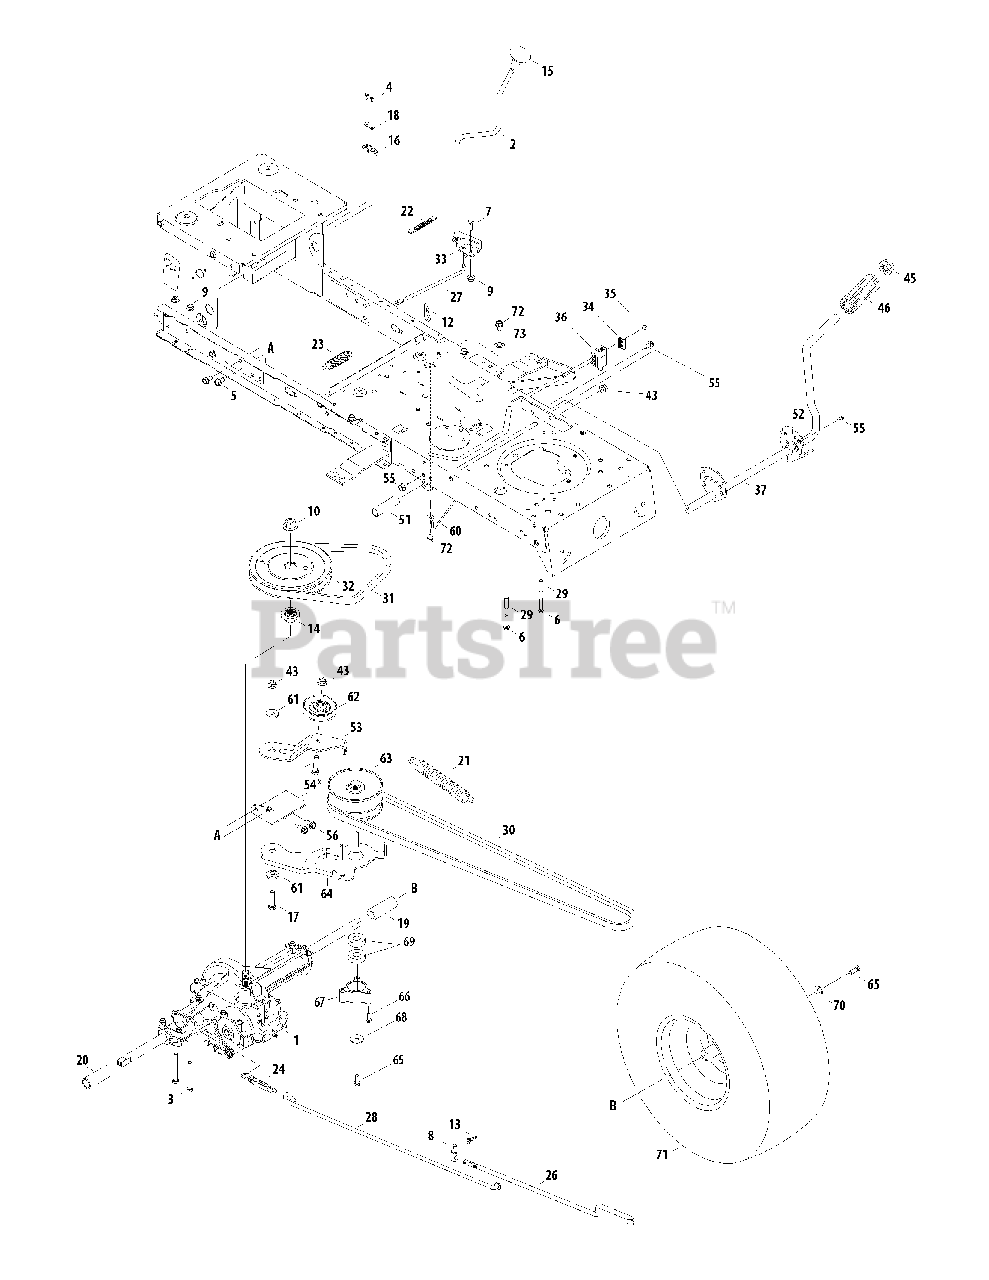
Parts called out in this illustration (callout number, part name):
1	Transmission Ass’y
2	Shift Lever Ass’y
3	Hex Screw 5/16-18 x 2.75
3	Hex Screw 5/16-18 x 3.5
4	Hex Wash HD AB S-Tapp Screw #8-.50
5	S-Tapp Screw 5/16-18 x .75
6	Hex Bolt 1/4-20 x 1.25
7	Hex Bolt 5/16-18 x .75" Lg. Gr. 5
8	Ferrule
9	Flange Locknut 5/16-18 Gr. F, Nylon
10	Flange Nut
12	Cotter Pin
13	Bow Tie Cotter Pin
14	Pulley Hub 5/8" Spline
15	Shift Knob
16	Short Spring Switch
17	Screw, 3/8-16 x 1.75
18	Insulator Nut Plate
19	Sleeve, .758 x .821 x 3.3125
20	Sleeve, .758 x .821 x 2.4375
21	Spring, Extension, .94 OD x 6.75
22	Spring, Extension
23	Spring, Extension, .80 OD x 3.28
24	Ext. Spring .59 OD x 4.00 Lg.
25	Flat Washer .344 ID x .625 OD x .063
26	Control Rod, Variable Speed
27	Shift Rod (38"/42")
28	Brake Rod
29	Spacer .260 x .375 x 1.030 Lg.
30	Belt 5L x 70.9" Lg.
31	Belt 5L x 35.25" Lg.
32	Pul ley, V-Type, 7.25 dia.
33	Shift Bracket, Ad just able
34	Switch Plate
35	Hex AB-Tap Screw #10 X .50" Lg.
36	Interlock Switch
43	Flange Lock-Nut 3/8-16 Gr. F Ny lon
45	Push Cap 5/8" Dia Rod
46	Foot Pad
51	Spacer .630 ID
53	Idler Bracket
54	Transmission Torque Bracket
55	Self-tapping Screw 5/16-18 x .625
56	Hex Wash. Hd. Screw. 5/16-18 x .75 Lg.
60	Belt Keeper Rod
61	Shoul der Spacer
62	Flat Idler
63	Vari able Speed Pul ley Ass’y 4.75 OD
64	Vari able Speed Bracket Ass’y
65	Hex L-Screw 5/16-24 x 0.75 Gr. 5
66	Hex Screww 1/4-20 x 1.5
67	Bearing Cup
68	Flat Washer .22 ID x 1.25
69	Ball Bear ing 17 x 40 x 12
70	Cupped Washer .345 ID x .88 OD x .060
71	Wheel Assembly Complete
72	Hex Wash S-Tapp Screw 1/4-20 x .50
73	Lockwasher 1/4"
